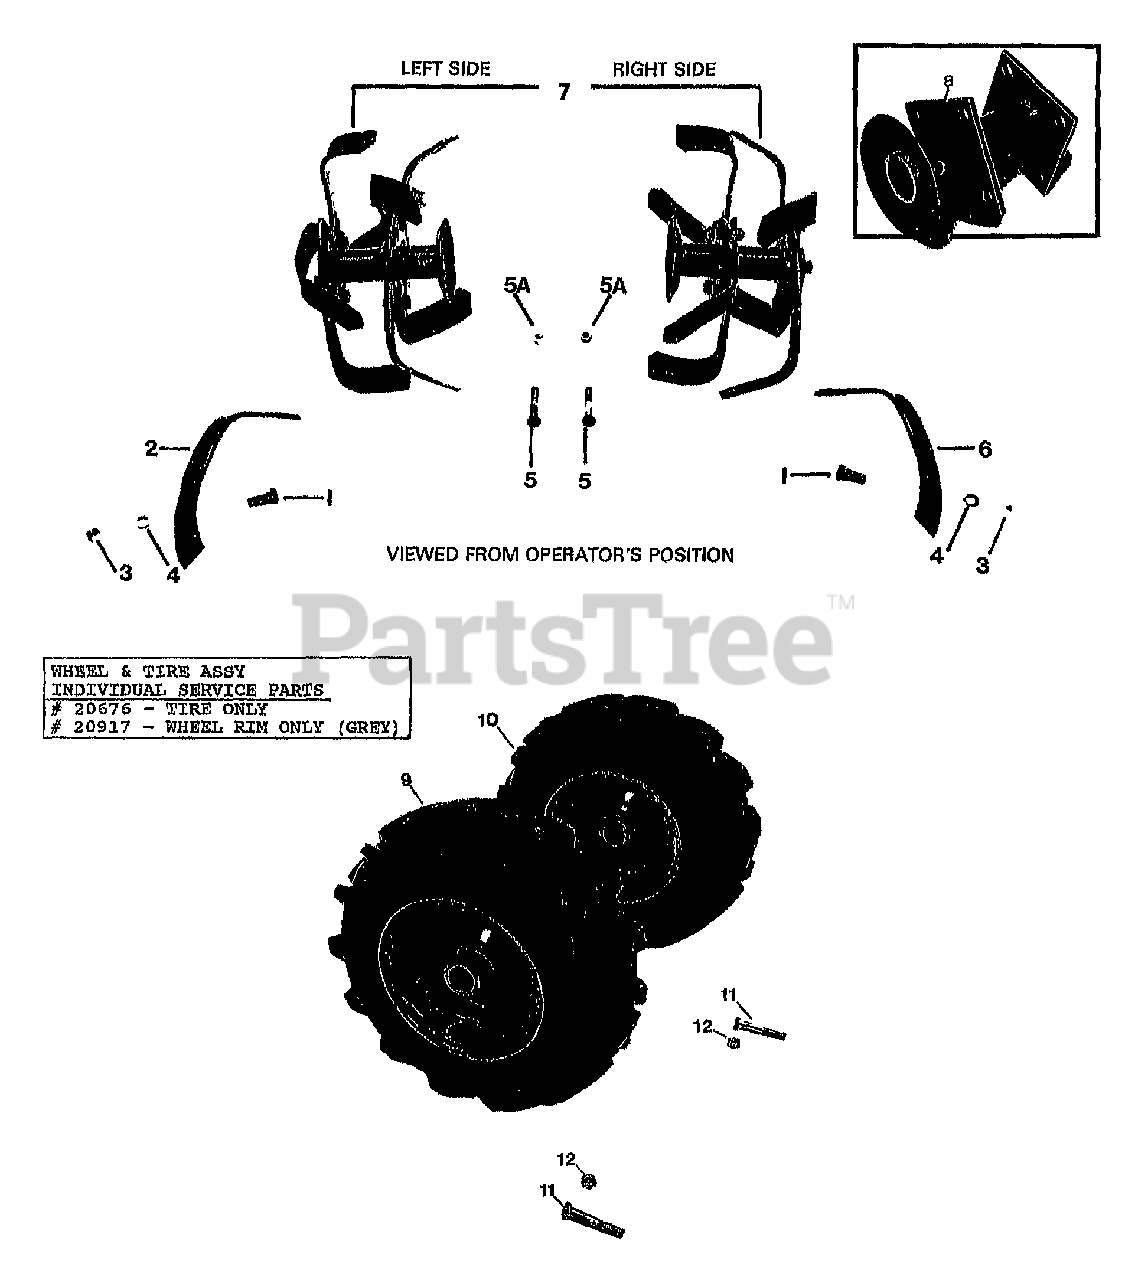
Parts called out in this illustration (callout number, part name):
1	SCR-HH 3/8-16X1.0 G5 ZP
2	TINE-BOLO RT W/HDW
3	NUT-HEX 3/8-16 ZP
4	WASHER-LK .375
5	SCR-HH 3/8-16X2.00 G8 (HOLDER TO TILLER SHAFT)
5A	NUT-H/LK 3/8-16
6	TINE-BOLO LT W/HDW
7	P-1 BOLO&HOLDS
8	TINE HOLDER (FOR BOLO TINES, LT & RT SIDES)
9	ASSM-TIRE LT 4.10 X 6" (10-20 LBS. AIR REQ'D)
10	ASSM-TIRE RT 4.10 X 6" (10-20 LBS. AIR REQ'D)
11	BOLT-HH 5/16-18 X 2 G5 ZP
12	NUT-H/LK 5/16-18
